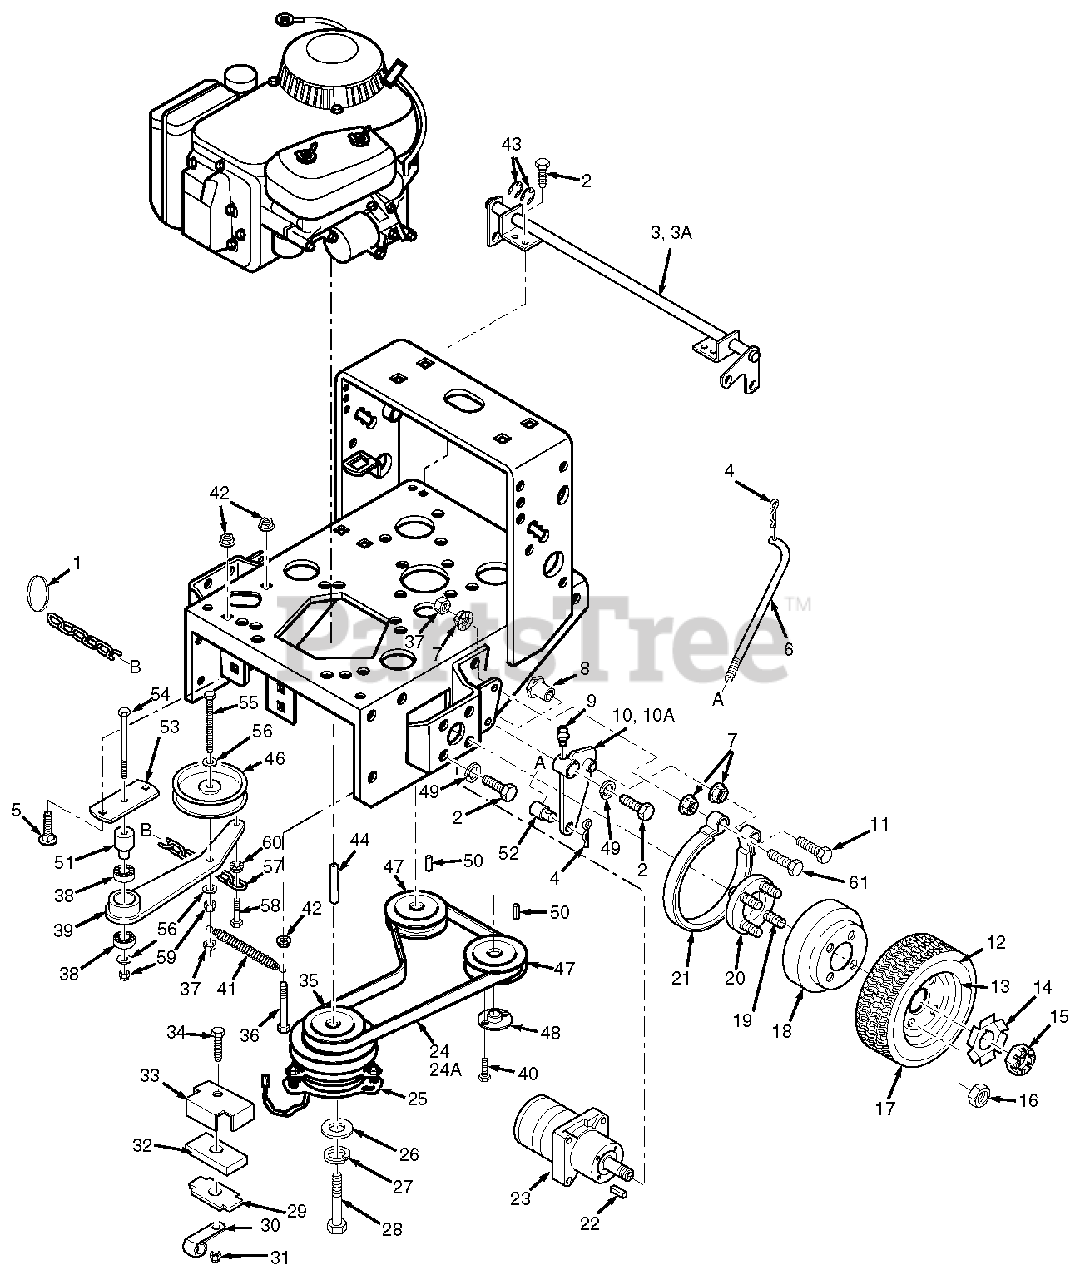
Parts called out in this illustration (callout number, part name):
1	Ring, Split
2	Bolt, 3/8-16 x 1" Hex Head
3	Brake Shaft Assembly Weldment, 16" Small Frame
3A	Brake Shaft Assembly Weldment, 20" Large Frame
4	Hair Pin Cotter, .094 x 1.62
5	Carrage Bolt, 5/16-18 x .75"
6	Rod, Brake Lower
7	Nut, 3/8-16 Serr. Flange
8	Bushing, Brake
9	Grease Fitting
10	Brake Actuator Weldment-LH
10A	Brake Actuator Weldment-RH
11	Bolt, 3/8-16 x 2-1/4"
12	Tire, 16 x 6.50, 4 ply
13	Rim Assy
14	Lock Washer, Wheel Motor
15	Hex Castle Nut, 3/4-28 UNEF
16	Nut, Lug
17	Wheel Assy.,
18	Brake Drum
19	1/2-20 Serrated Bolt
20	Hub, Wheel
21	Brake Band, 7.5"
22	Key, 3/16 X .75 Woodruff
23	Wheel Motor
24	Belt, Pump Drive, 16" Small Frame
24A	Belt, Pump Drive, 20" Large Frame
25	Electric Clutch
26	Flat Washer .469 x 1.75 x .25
27	Lock Washer, 7/16"
28	Hex Head Bolt, 7/16-20 x 2-3/4"
29	Plate, Backing
31	Nut, 5/16-18 Elastic Stop
32	Rubber Pad, Clutch Stop
33	Retainer, Clutch Stop
34	Hex Head Bolt, 5/16-18 x 1.75"
35	Pulley, Pump Drive Engine
36	Hex Head Bolt, 5/16-18 x 2.75"
37	Nut, 3/8-16 Center Lock
38	Ball Bearings
39	Idler Arm Weldment, Pump
40	Bolt, Hex Head 1/4-20 x 1" Grd 8
41	Spring, Pump Belt Idler
42	Nut, 5/16-18 Serr. Flange
43	Retaining Ring, 3/4" Ext. "E"
44	Key, 1/4x1/4 x 3.75"
45	Flat Washer, 3/8"
46	Pulley, Idler 4.5"
47	Pulley, Pump Shaft
48	Tapered Hub
49	Lockwasher, 3/8"
50	Key, 5.0 x 5.0 x 25mm
51	Pivot, Idler (Long)
52	Swivel Joint
53	Base, Idler Pivot
54	Bolt, Hex Head 3/8-16 x 3"
55	Bolt, Hex Head 3/8-16 x 2.75"
56	Flatwasher 3/8"
57	Chain
58	Bolt, Hex Head 1/4-20 x 1.25"
59	Nut, Hex Elastic Stop 3/8-16
60	Nut, Serrated Flange 1/4-20
61	Bolt, Hex Head 3/8-16 x 2.63"
